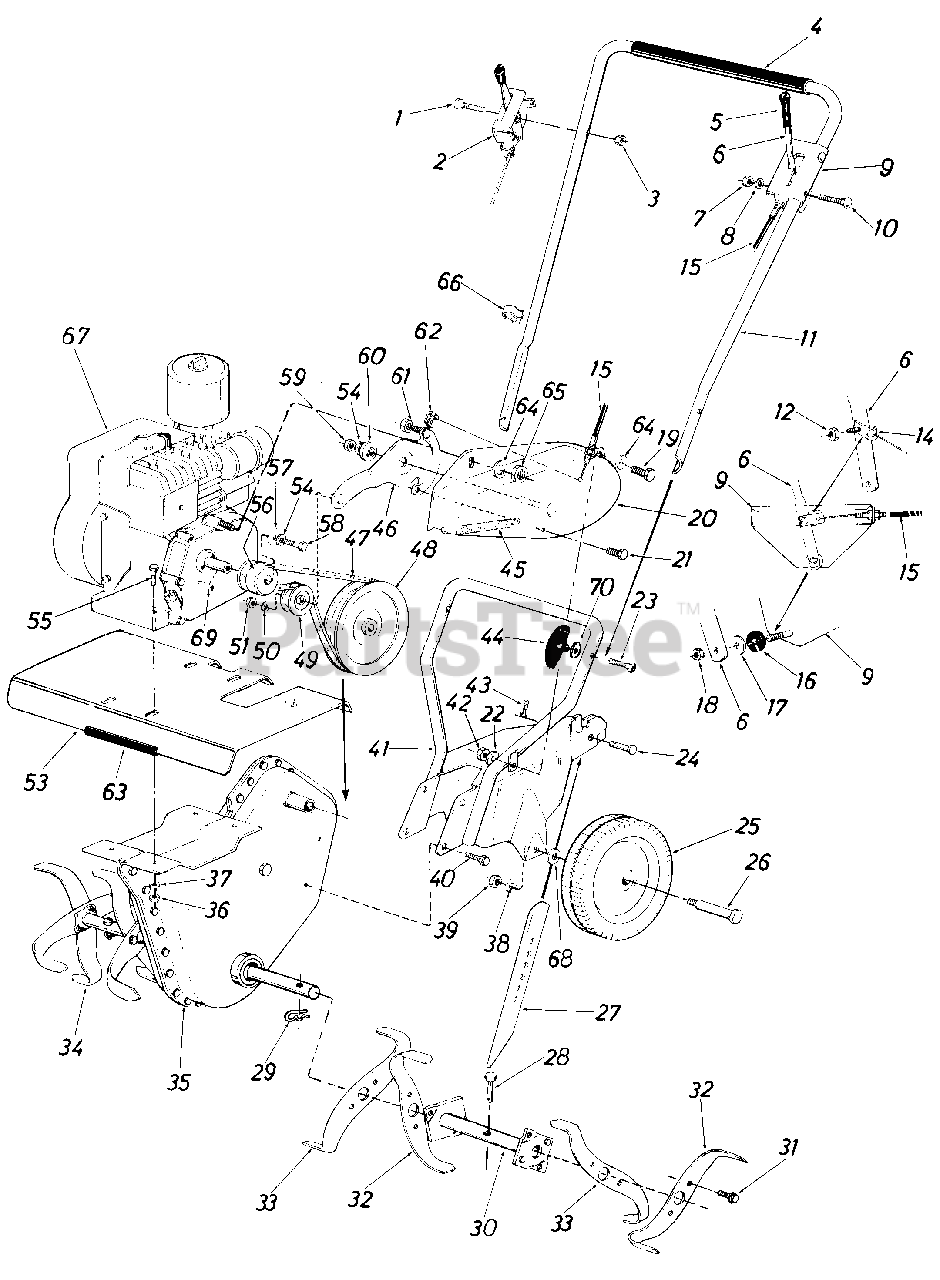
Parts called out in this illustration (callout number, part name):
1	Hex Bolt 1/4-20 x 1.50" Lg.
2	Throttle Control Ass'y. Comp.
3	Hex Cent. L-Nut 1/4-20 Thd.
4	Grip 14" Lg.
5	Handle Grip
6	Clutch Handle Ass'y.
7	Hex Cent. L-Nut 1/4-20 Thd.
8	Fl-Wash. 1/4" I.D. x .50" O.D. x .063
9	Clutch Handle Brk't. Ass'y.
10	Carr. Bolt 1/4-20 x 1.25" Lg.
11	Upper Handle
12	Hex Cent. L-Nut 1/4-20 Thd.
14	Clevis
15	Clutch Cable
16	Rubber Wash.
17	Fl-Wash. 1/4" I.D. x .75" O.D. x .063
18	Hex Cent. L-Nut 1/4-20 Thd.
19	Hex Bolt 1/4-20 x .75" Lg.
20	Belt Cover Ass'y.
21	Hex Wash. Hd. Tap Scr. 1/4 x .50
22	L-Wash. 1/4" I.D.s
23	Curved Hd. Bolt 5/16-18 x 1.75" Lg.
24	Clevis Pin
25	Wheel Ass'y. 7"
26	Shoulder Boit
29	Hairpin Cotter
36	Hex Nut 5/16-18 Thd.*
37	L-Wash. 5/16" Scr.*
38	L-Wash. 3/8" Scr. H.D.
39	Hex Cent. L-Nut 3/8-16 Thd.
40	Hex Wash. SF-Tap Scr. 5/16-18 x .50" Lg.
43	Intern. Cotter Pin
44	Hand Knob
45	Extension Spring .60 O.D. x 4.88" Lg.
46	Idler Arm Ass'y.
47	Belt 3/8 x 29" Lg.
48	Chain Case Pulley 5-1/2 x 1/2"
49	Fl-Idler 2"
50	L-Wash. 5/16" Scr.*
51	Hex Nut 3/8-24 Thd.*
55	Hex Bolt 5/16-18 x 1.50" Lg.
56	Engine Pulley 3/8 V x .7525 I.D. x 2" O.D.
57	Fl-Wash. .385 I.D. x 1.00" O.D. x .135
58	Hex Bolt 3/8-24 x 1.00" Lg.*
59	Hex Nut 5/16-18 Thd.*
60	Shld. Spacer.50" Dia. x .133
61	Hex Cent. L-Nut 1/4-20 Thd.
62	Clevis
63	Trim Strip 4"
64	L-Wash. 1/4" I.D.*
65	Hex Cent. L-Nut 1/4-20 Thd.
66	Cable Tie
67	Engine
68	Be I l-Wash .
69	Square Key 3116 x 314" Lg.
70	Belleville Washer
